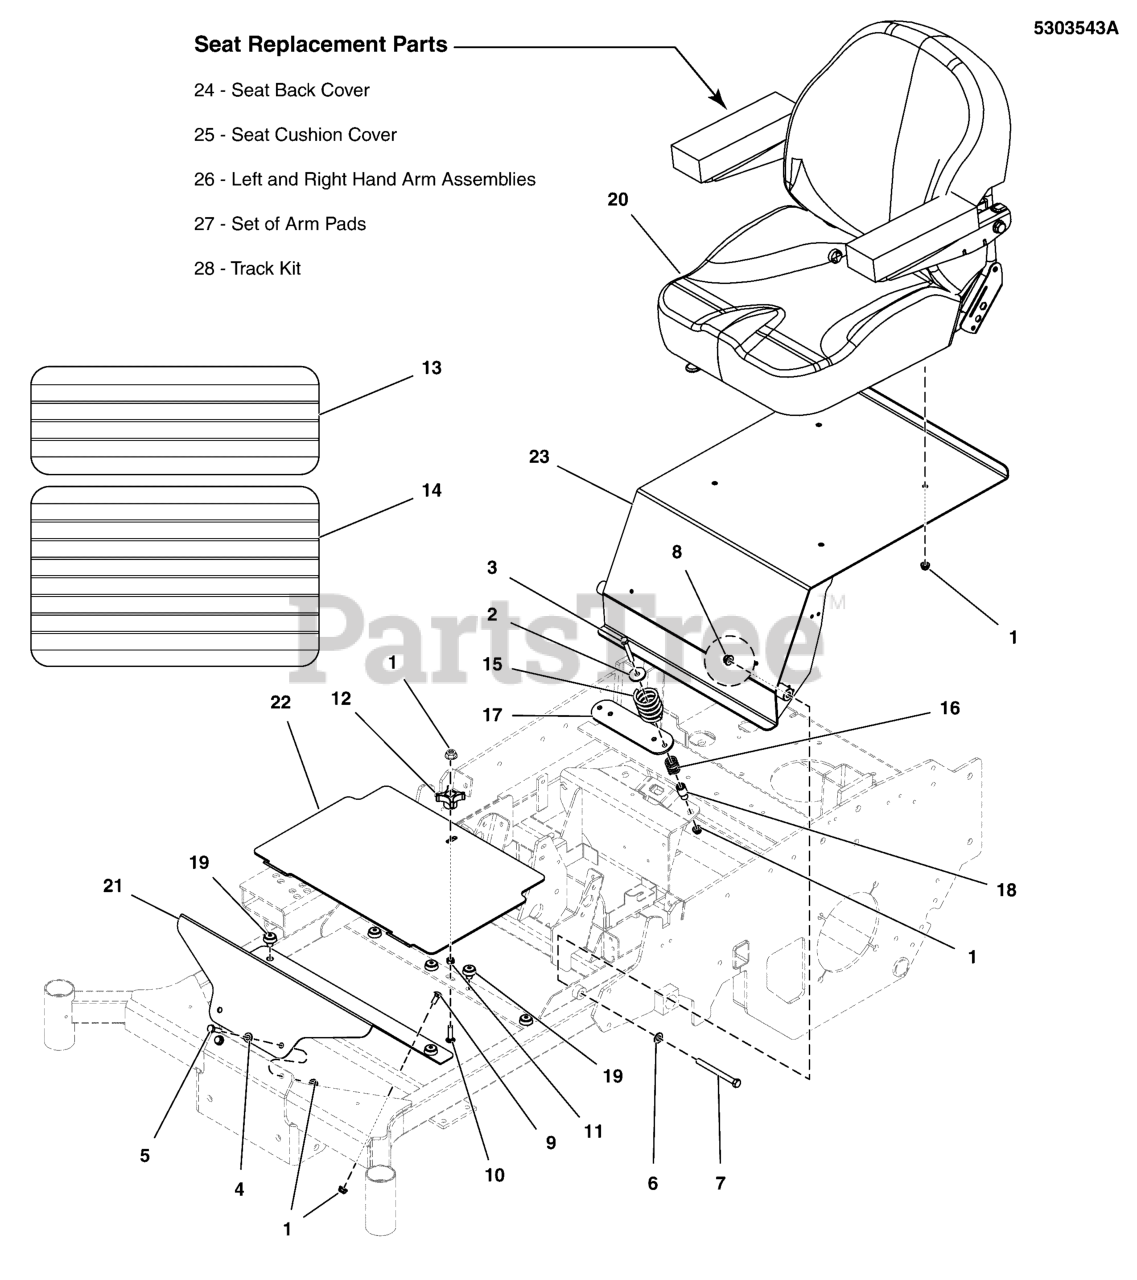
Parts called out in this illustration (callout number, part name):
1	NUT, 5/16-18 HEX NYLOCK FLANGE NUT
2	WASHER, .34 X 1.25 X 10 GA
3	* BOLT, 5/16-18 X 2-1/4 GD5 YZ
4	WASHER, 5/16" SAE
5	BOLT, 5/16-18 X 1" GRD5 YZ
6	WASHER, 3/8 SAE
7	BOLT, 3/8-16 X 4" GD5 CZ
8	NUT, 3/8 - 16 HEX NYLOCK FLANGE
9	BOLT, 5/16-18 X 3/4, CARRIAGE, GD5, CZ
10	BOLT, 5/16-18 X 1-1/4, CARRIAGE, GD5, CZ
11	NUT, 5/16-1/8, HEX, CNTR LK, ZINC PHOS/OIL
12	KNOB-INT THR .312-18 4-ARM 2.12WD 1.06LG
13	SAFETY WALK, FLOOR REST, 16.00 X 6.00
14	SAFETY WALK, FLOOR PLATE, S50X, 10X17.13
15	SPRING, SEAT SUPPORT
16	SPRING-COMP, .720ID X 1.310LG X .118 WIRE
17	PLATE, SEAT SWITCH - RED
18	SPACER, .33 X .66 X 1.31 SHLDR, CZ
19	MNT, VBRTN, RBBR
20	SEAT, CI3, SEAT'S INC. 2016
21	PLATE, FLOOR, NON REMOVABLE - RED
22	PLATE, FLOOR, REMOVABLE, S125XT - RED
23	ASSM, SEAT PLATE W/ DECALS, S150XT-DOM (5413405D)
24	BACK, COVER, CI3 SEAT
25	CUSHION COVER, CI3 SEAT
26	LEFT AND RIGHT HAND ARM ASSEMBLIES, CI3 SEAT
27	ARM PAD, C13 SEAT
28	TRACK KIT, CI3 SEAT
